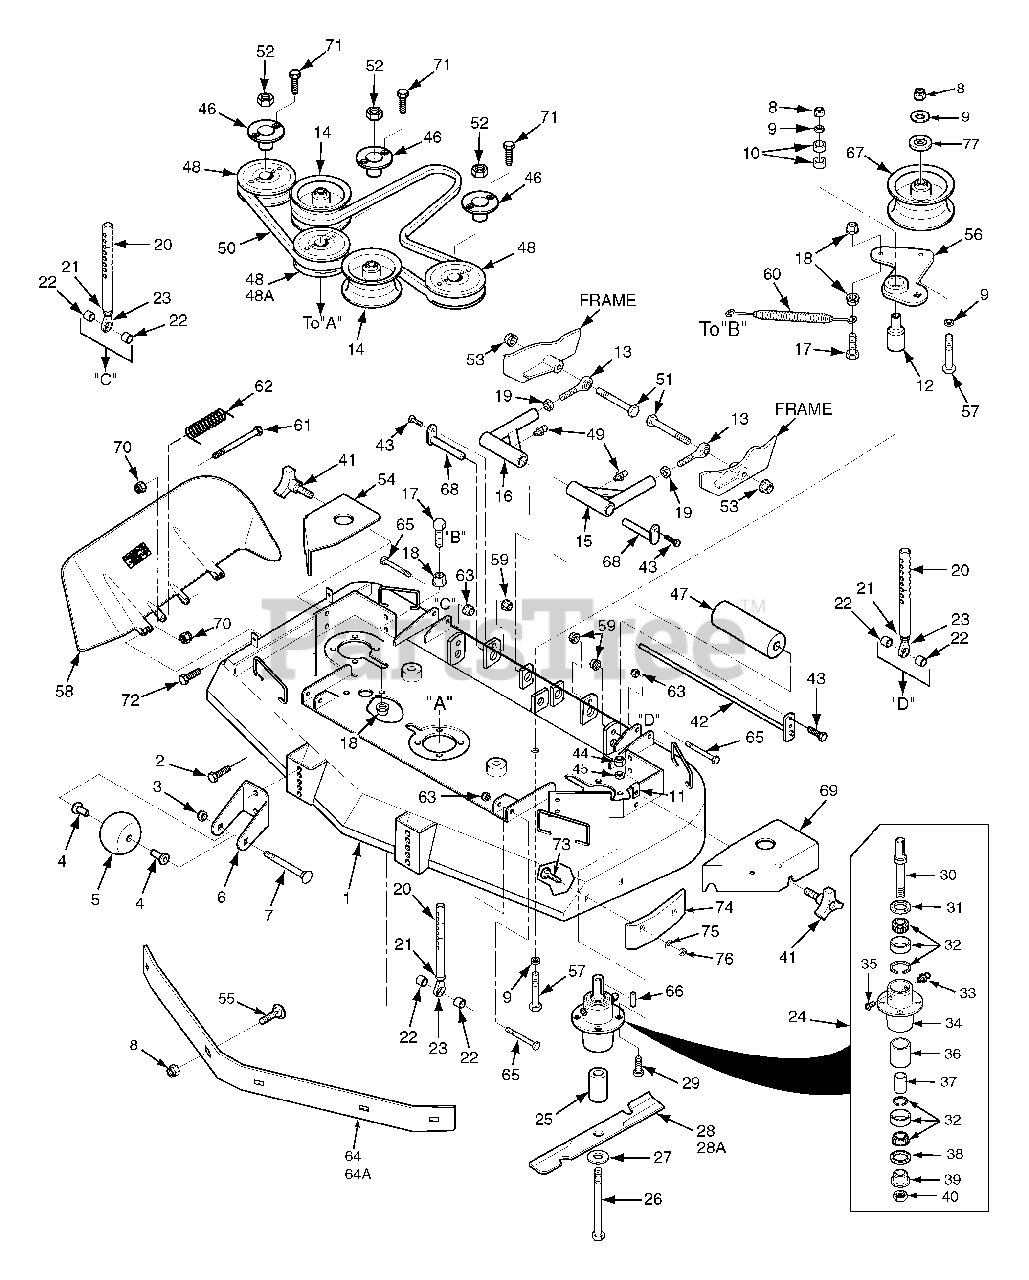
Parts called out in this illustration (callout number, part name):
1	Cutter Deck W/ Decals
2	Capscrew, 3/8-16 x 1" Serr. Flng.
3	Lock Nut, 3/8-16 Center Lock
4	Bushing, .376" ID Oilite
5	Wheel, Anti-Scalp
6	Bracket, Anti-Scalp Wheel
7	Bolt, Carriage 3/8-16 x 4"
8	Hex Nut, 3/8-16 Elastic Stop
9	Flatwasher, 3/8" (.938 x .391 x .105)
10	Ball Bearings
11	U-Nut, 3/8-16
12	Pivot, Idler
13	Rod End, Male 1/2-20 RH Thread
14	Pulley, Idler
15	Push Arm - LH
16	Push Arm - RH
17	Capscrew, Hex Head 3/8-16 x 1-1/2"
18	Nut, 3/8-16 Serrated Flange
19	Nut, 1/2-20 Jam
20	Pin Assembly
21	Nut, 3/8-24 Jam
22	Spacer, Deck Adjustment Pin
23	Rod End, Male 3/8-24
24	Spindle Assembly
25	Spacer, Spindle
26	Bolt,Hex Head 5/8-11 x 9-1/2"
27	Flatwasher, 5/8 W
28	Cutter Blade 18"
28A	Cutter Blade 18" Hi Lift
29	Bolt, Hex Head 5/16-18 x 1-3/4" Gr 8
30	Spindle Shaft
31	Seal, Cutter Spindle - Top
32	Tapered Bearings (Two)
33	Grease Fitting
34	Spindle Housing
35	Relief Fitting, Cutter Spindle
36	Spacer Outside
37	Spacer, Inside
38	Seal, Cutter Spindle - Bottom
39	Spindle Bushing
40	Nut, Spindle
41	Wing Nut, 3/8-16
42	Roller Shaft
43	Bolt, Hex Head 5/16-18 x 1"
44	Hex Nut, 5/16-18 Elastic Stop Gr. 8
45	Lock Washer 5/16"
46	Tapered Hub
47	Guide, Roller
48	Pulley, 5.75 O.D.
49	Grease Fitting, 90 Degree
50	Belt, Deck Drive
51	Bolt, Hex Head 1/2-13 x 3"
52	Hex Nut, 5/8-11
53	Hex Nut, 1/2-13 Elastic Stop
54	Belt Cover, RH
55	Bolt, Carriage 3/8-16 x 1"
56	Idler Arm Weldment
57	Capscrew, Hex Head 3/8-16 x 3"
58	Discharge Chute
59	Nut, 5/16-18 Serrated Flange
60	Spring, Deck Idler
61	Bolt, Hex Head 5/16-18 x 4-1/4"
62	Spring, Chute Return
63	Nut, 3/8-16 Elastic Stop
64A	Baffle Weldment 52V
65	Bolt, Hex Head 3/8-16 x 2-1/2"
66	Key, 1/4" x 1/4" x 2"
67	Pulley, Idler
68	Push Arm Shaft
69	Belt Cover LH
70	Hex Nut, 5/16-18 Elastic Stop
71	Bolt, Hex Head 1/4-20 x 1" Gr. 8
72	Bolt, Hex Head 5/16-18 x 1-1/2"
73	Bolt, Carriage 5/6-18 x 3/4"
74	Pad, Deck Wear
75	Flatwasher, 5/16"
76	Hex Nut, 5/16-18 Center Locknut
77	Dust Shield
